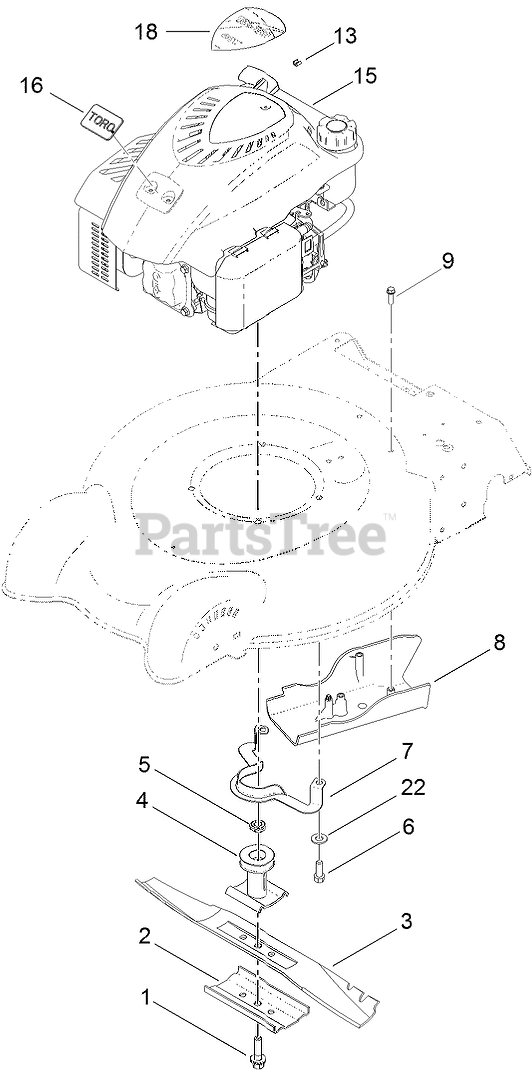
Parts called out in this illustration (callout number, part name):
1	BOLT-BLADE
2	SUPPORT-BLADE
3	BLADE-20 INCH
4	DRIVER-BLADE
5	Spacer-Driver
6	SCREW-TAPTITE
7	Guide-Belt
8	COVER-BELT
9	SCREW-HWH
13	STOP-ROPE
15	ENGINE-LC1P65FA
16	PLATE-LOGO, TORO
18	DECAL-SHROUD
22	WASHER-FLAT
